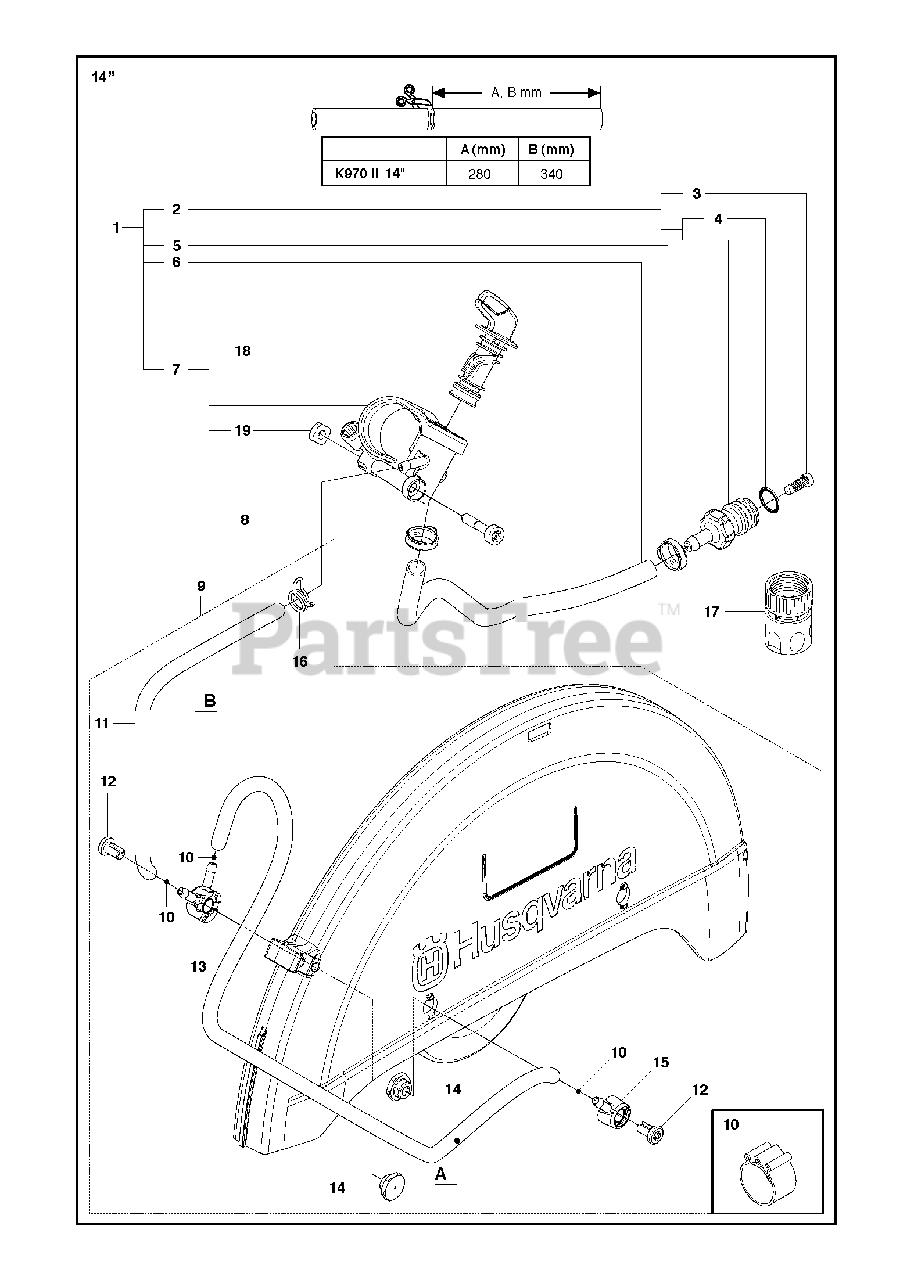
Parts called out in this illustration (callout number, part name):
1	HOSE KIT
5	HOSE CLAMP
8	SCREW ITXSCM
10	HOSE CLAMP
12	SCREW ITXSCM
18	LEVER ASSY
